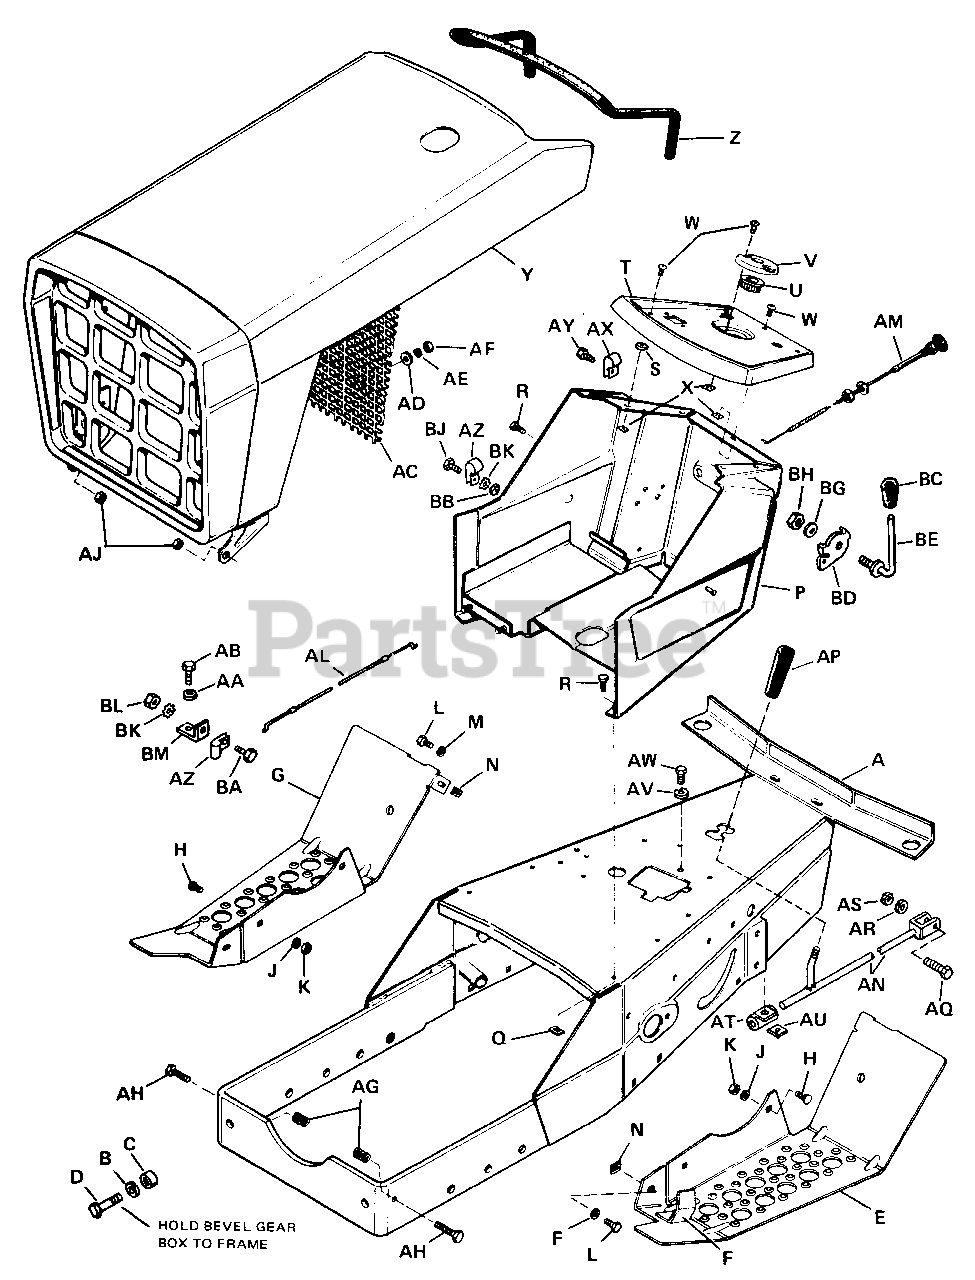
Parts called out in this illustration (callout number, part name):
A	Frame Assy.
B	Lock Washer, 7/16"
D	Hex Cap Screw, 7/16"-14 N.C. x 1-1/2"
E	Foot Rest R.H.
F	Guard Assy.
G	Foot Rest L.H.
H	Carriage, Bolt, 5/16"-16 N.C. x 3/4"
J	Lock Washer, 5/16"
K	Hex Nut, Full, 5/16"-18 N.C.
L	Hex Cap Screw 5/16"-18 N.C. x 3/4"
M	Lock Washer, 5/16"
N	Nut, Tinnerman, 5/16"-18 N.C.
P	Dash Assy.
Q	Nut, Tinnerman
R	Hex Head Self Tapping Screw, No. 14 AB x 3/4"
S	Plain Washer
T	Panel, Instrument
U	Bushing, Steering
V	Plate, Steering Adj.
W	Round Head Phillips Screw, 1/4" 20 N.C. x 1/2"
X	Nut, Tinnerman, 1/4"-20 N.C.
Y	Grille & Hood Assy.
Z	Molding, Hood
AA	Lock Washer
AB	Self Tapping Rec. Hex. Hd. Screw
AC	Screen, Grille
AE	Lock Washer, Shakeproof No. 10
AF	Nut, Hex Full, No. 10-24 N.F.
AH	Hex Cap Screw, 3/8"-16 N.C. x 1-1/2"
AJ	Hex Lock Nut, Center, 3/8"-16 N.C.
AL	Throttle Control
AM	Choke Control
AN	Rod Assy. Shifter
AQ	Hex Capscrew, 5/16"-18 N.C. x 1-1/2" SAE Grade 8
AR	Lock Washer, 5/16"
AS	Full Hex Nut, 5/16"-18 N.C.
AT	Guide Assy. Shift Rod
AU	Nut, Retainer
AV	Lock Washer, 1/4"
AW	Hex Capscrew, 1/4"-20 N.C. x 5/8" SAE Grade 5
AX	Clip, Bowden Wire
AY	Self Tapping Screw Rd. H., No. 10-24 N.C. x 1/2"
AZ	Clip, Bowden Wire
BA	Screw Mach. Rd. Hd., No. 10-32 N.F. x 3/8"
BB	Full Hex Nut, No. 10-32 N.F.
BC	Throttle Handle
BD	Stop Throttle
BE	Arm Throttle
BG	Washer Lock Dished Type, 3/8"
BH	Full Lock Hex Nut, 3/8"-16 N.C.
BJ	Screw Rd. Hd. Mach, No. 10-32 N.F. x 1/2"
BK	Washer, External No. 10 Shakeproof
BL	Full Hex Nut, No. 10-32 N.F.
BM	Bracket, Throttle Cable
